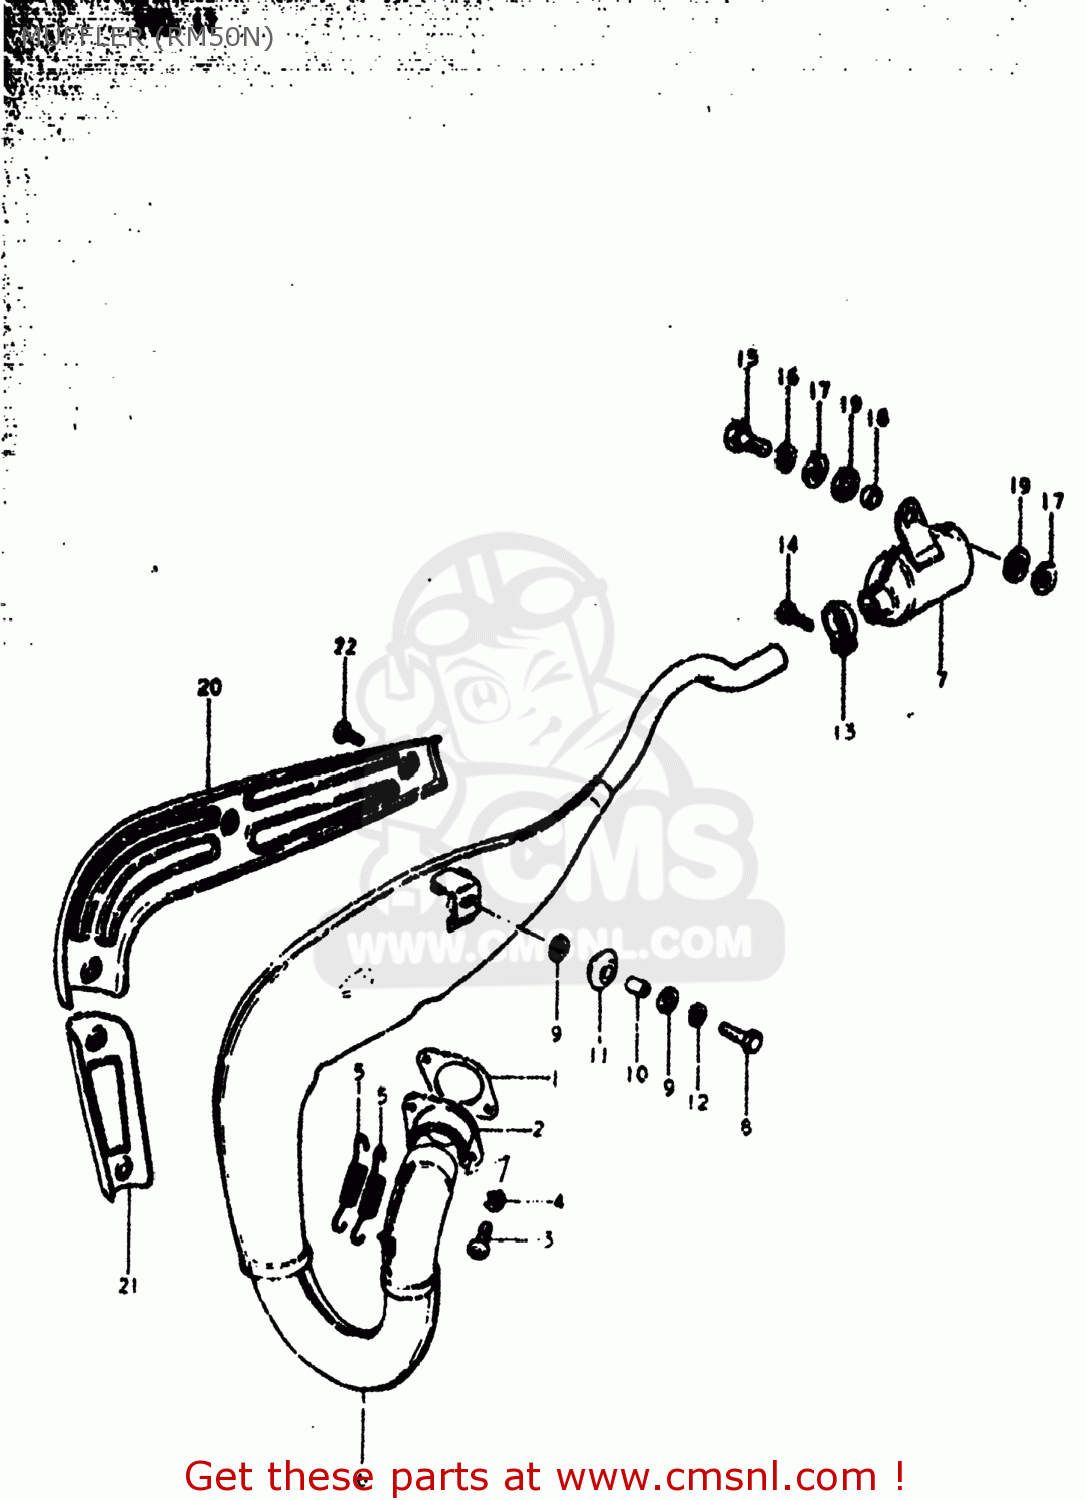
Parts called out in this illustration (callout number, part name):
1	GASKET,EXHAUST PIPE (MCA)
2	PIPE,CENTER EXHAUST
3	SCREW
4	LOCK WASHER
5	SPRING
6	BODY,MUFFLER
7	BODY,MUFFLER
8	BOLT
9	WASHER
10	WASHER(8.2X23X3.2)
11	DAMPER,MUFFLER,FR
12	LOCK WASHER
13	CLAMP
14	BOLT(6X20)
15	BOLT
16	WASHER,LOCK,8.
17	WASHER
18	SPACER (8.6X13.8X9)
19	CUSHION
20	COVER,MUFFLER NO.1
21	COVER,MUFFLER
22	SCREW
